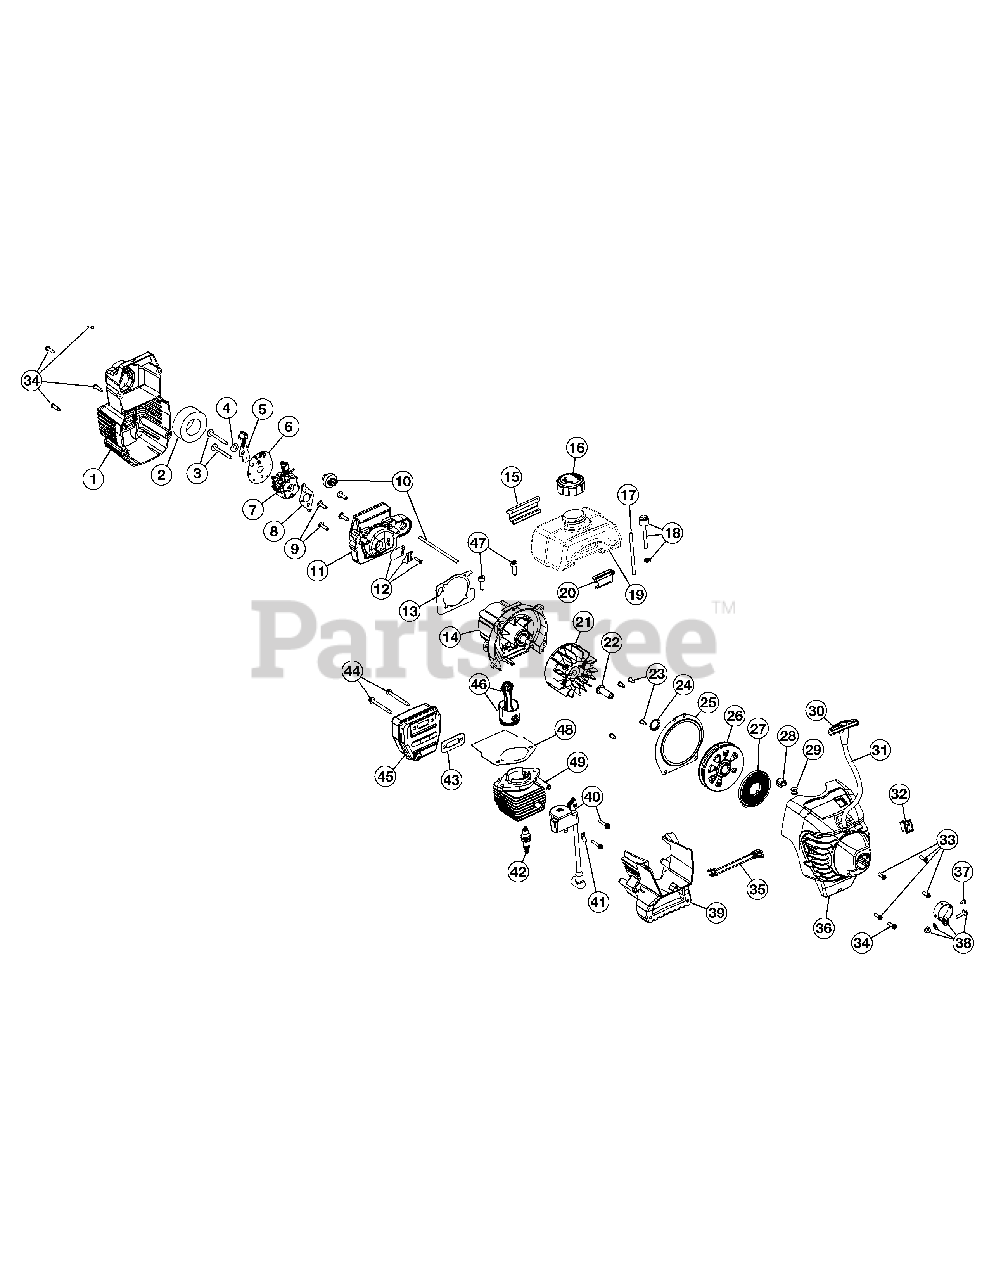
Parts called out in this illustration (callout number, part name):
1	Air Cleaner Cover Assembly (includes 2 & 34)
2	Air Cleaner Filter
3	Carburetor Mounting Screws
4	Wavey Washer
5	Choke Lever Assembly
6	Choke Lever & Plate (includes 5)
7	Carburetor Assembly (includes 8 & 18)
8	Carburetor Gasket
9	Carb Mount Screw
10	Primer and Hose Assembly
11	Carburetor Mount Assembly (includes 9, 12 & 13)
12	Reed Assembly
13	Carburetor Mount Gasket
14	Crankcase Service Assembly (includes 9)
15	Rear Mounting Pad
16	Fuel Cap Assembly
17	Fuel Return Line
18	Fuel Line Assembly
19	Fuel Tank Assembly (includes 16-18)
20	Front Mounting Pad
21	Flywheel Assembly
22	Square Nut Drive
23	Plate Screw
24	Palnut
25	Pressure Plate (includes 23 & 28)
26	Recoil Pulley Assembly (includes 24 and 31)
27	Recoil Spring
28	Eyelet Retainer
29	Rope Guide
30	Pull Handle
32	Switch Assembly
33	Housing Screw
34	Cover Screw
35	Wire Lead
36	Starter Housing Assembly (includes 23-35)
37	Anti-Rotation Screw
38	Clamp Assembly (includes 37)
39	Shroud Extension and Stand (includes 34)
40	Module Assembly
41	Ground Tab
42	Spark Plug
43	Exhaust Gasket
44	Muffler Mounting Bolt Assembly
45	Muffler Assembly (includes 43, 44, and spark arrester)
46	Piston & Rod Assembly
47	Cylinder Bolt
48	Cylinder Gasket
49	Cylinder Assembly (includes 47 & 48)
